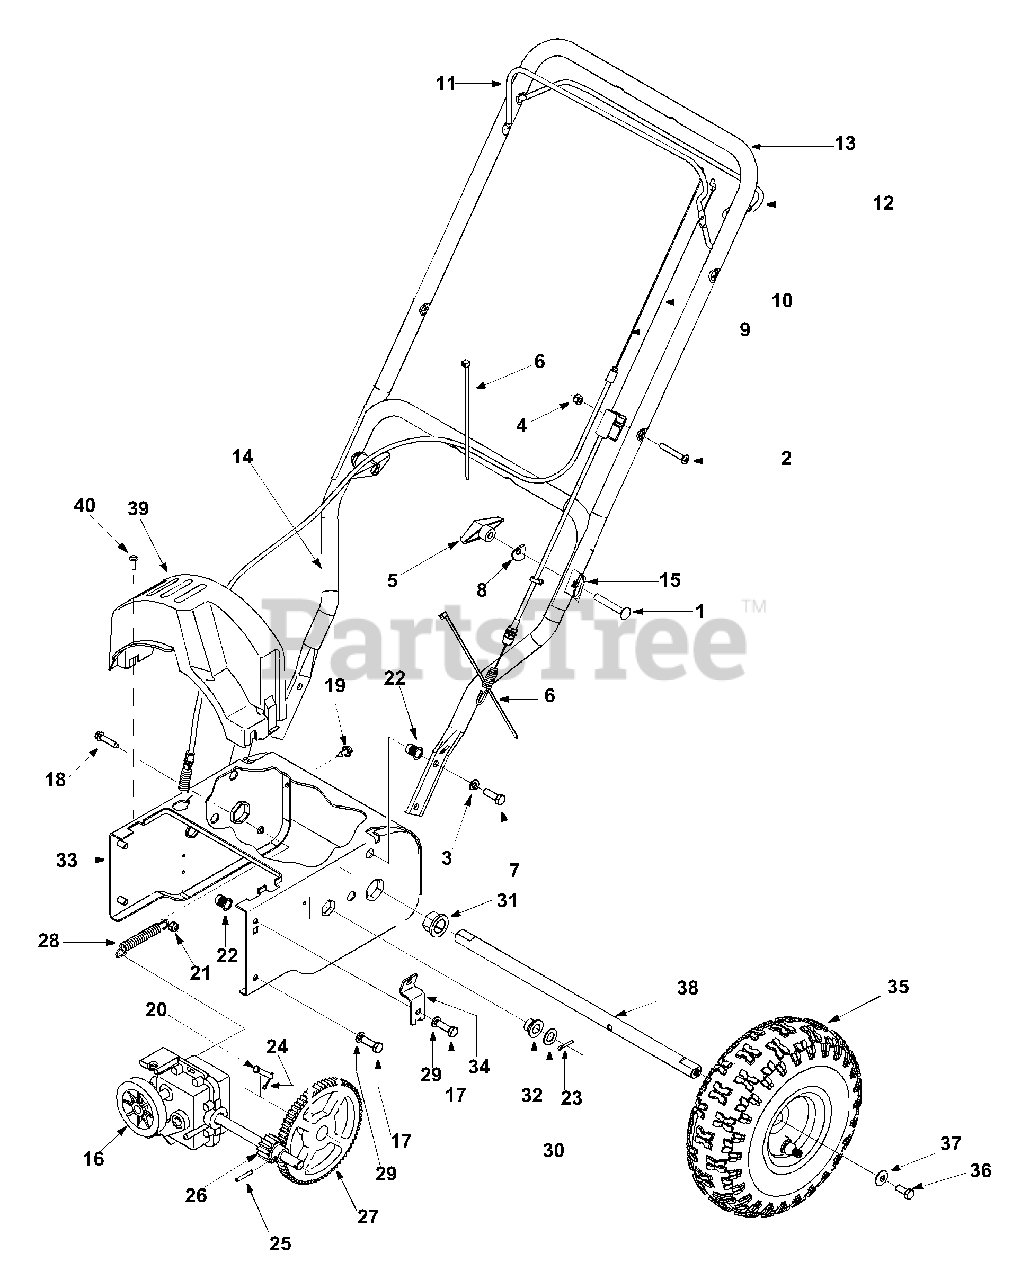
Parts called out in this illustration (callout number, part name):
1	Carriage Screw 5/16-18 x 2.25"
2	Mach. Screw 1/4-20 x 1.825"
3	Hex Bolt 5/16-18 x 1.0"
4	Hex Lock Nut 1/4-20
5	Handle Knob Assembly
6	Cable Tie
7	Lock Washer
8	Saddle Washer
9	Auger Cable
10	Drive Cable
12	Drive Bail
15	Handle Tab
16	Transmission Assembly
17	Hex Bolt 5/16-18 x 1.0"
18	TT Screw 1/4-20 x 1.25"
19	TT Screw 1/4-20 x .625"
20	Clevis Pin
21	Hex Lock Nut 1/4-20
22	Nut Insert
23	Cotter Pin
24	Cotter Pin
25	Roll Pin
26	Pinion 14T
27	Gear 70T
28	Extension Spring
29	Lock Washer
30	Flat Washer
31	Hex Flange Bearing
32	Hex Flange Bearing
36	Lock Bolt 5/16-24 x 0.75"
37	Bell Washer
38	Axle
39	Belt Cover
40	Self-Tapping Screw
